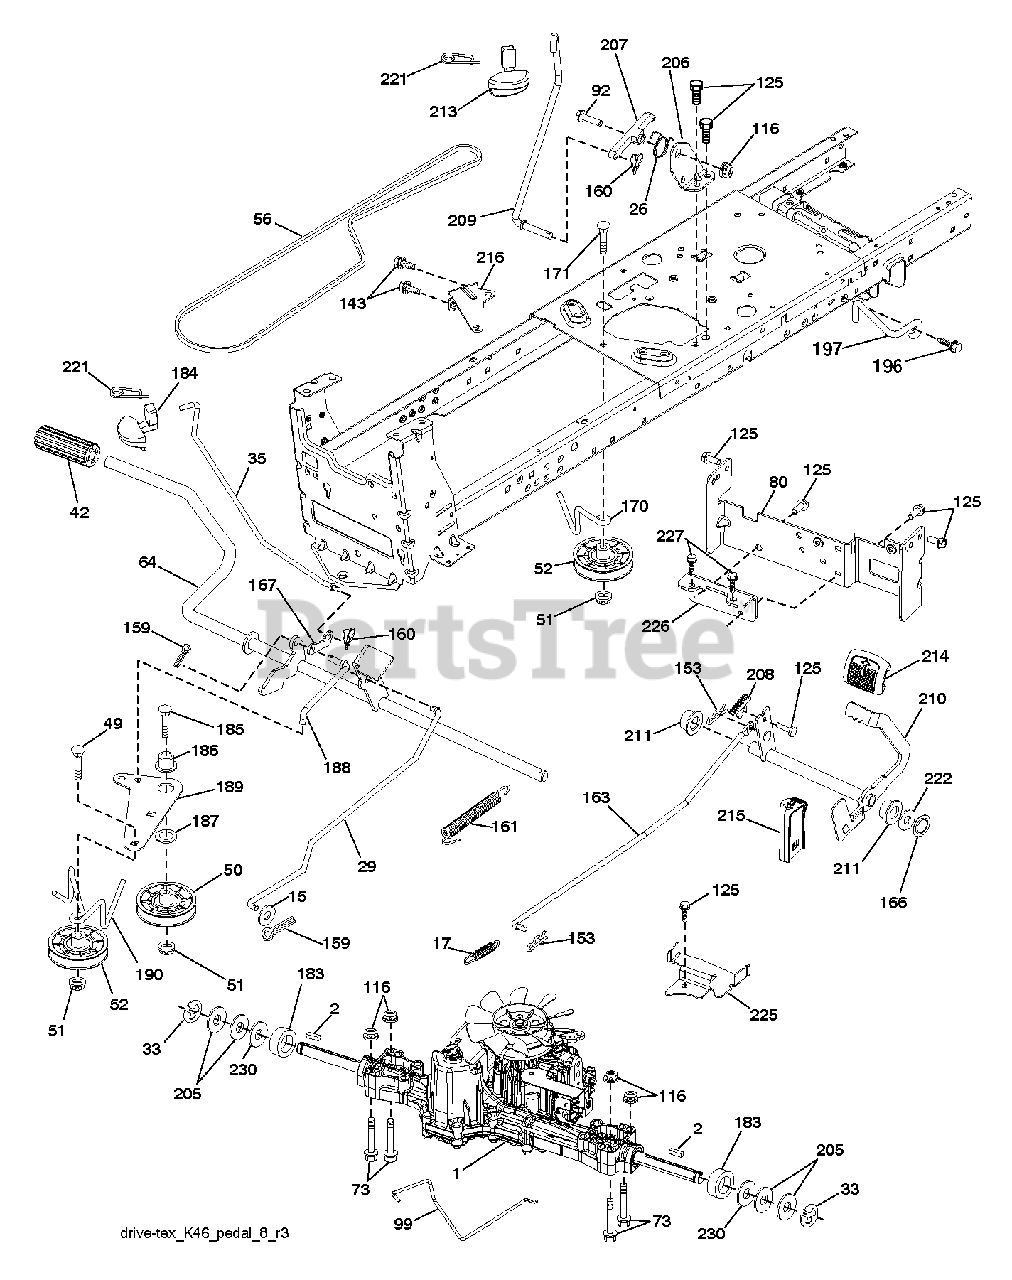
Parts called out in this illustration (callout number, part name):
1	TRANSAXLE(K46BT).PDL.
2	SQUARE KEY
15	WASHER
17	SPRING.BRAKE.K46.GREEN
26	SPRING.RETURN.CRUISE
29	ROD.BRAKE.K46
35	ROD.BRAKE.PARTK.HUSQ.TEX
42	PEDAL COVER T
50	IDLER.FLAT.910.OFFSET
51	NUT LOCK FLG 3/8-16 UNC
52	IDLER.V-GROOVE.910.OFFSET
56	V-BELT.MOWER.92.40.42/K46
64	SHAFT.ASM.PEDAL.BRK.CNTR
73	BOLT
80	STRAP TORQUE
92	BOLT
99	ROD.SPRING.BYPASS.K46.LT.Z
116	NUT LOCK HEX FLANGE 5/16-18
125	SCREW
143	SCREW LT
153	RETAINER M
159	COTTER PIN
160	RETAINER CLIP
161	SPRING, RETURN LT
163	ROD.CONTROL.PEDAL.K46
166	NUT.PUSH.625
167	LATCH.BRAKE.SPRING
170	KEEPER.BELT.ENGINE.4.2
171	BOLT
183	SPACER AXLE
184	HANDLE.PARKG.BRK.HUSQ X667
186	SPACER.RETAINER
187	WASHER 12/32X2X10GA
188	RP LINK.CLUTCH.GROUND.DRIVE
189	BELLCRANK.GROUND.DRIVE.TEX.
190	KEEPER.BELLCRANK.DRIVE
196	SCREW 3/8-16X1
197	LINK.CLUTCH.ANIT-ROTAT
206	BRKT.MOUNT.LATCH.CRUIS
207	LATCH.CONTROL.CRUISE
208	GEAR.SECTOR.CONTROL.CR
209	ROD.CONTROL.CRUISE.GT.
210	ROCKER.ASM.PEDAL.CONTR
211	BEARING.NYLON
213	KNOB.CONTROL.CRUSIE.HU
214	PEDAL.FORWARD.PAD.TEX
215	PEDAL.REVERSE.TEX.GT.4
216	BRACKET.PULLEY.IDLER.W/TEX
221	RETAINER.SPRING.CLIP.H
222	WASHER 21/32 X 1-1/4 X 10 GA.
225	KEEPER.BELT.TRANSAXLE.K46
226	BRACKET.MOUNT.TORQUE.K46.TLT
227	SCREW
230	WASHER.HARDENED
